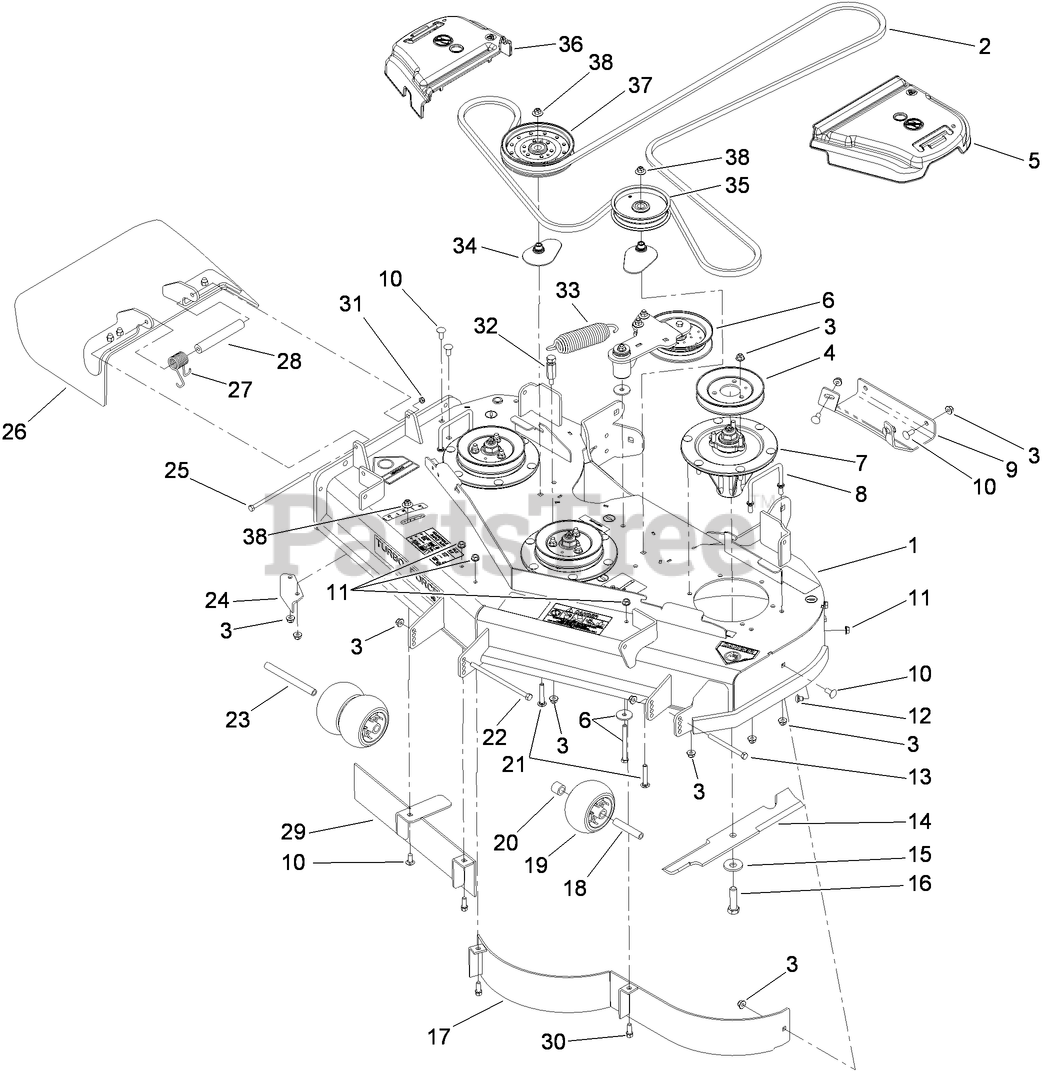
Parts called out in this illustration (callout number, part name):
1	DECK DECAL ASM
2	BELT-V
3	NUT-HF, NI
4	PULLEY
5	COVER-BELT, LH
6	IDLER ARM ASM
7	SPINDLE ASM
8	WIREFORM-COVER
9	PLATE-SKID
10	SCREW-CARR
11	NUT-HHF, WHIZ
12	SCREW-CARR
13	SCREW-HH
14	BLADE-16.5 INCH (HIGH FLOW)
15	Washer-Blade Bolt, Heavy
16	SCREW-BLADE
18	TUBE-SPANNER
19	ROLLER-SCALP, ANTI
20	TUBE-SPACER
21	BOLT-CARR, SHORT NECK
22	SCREW-HH
23	SPACER-WHEEL
24	BAFFLE-DISCHARGE
25	SCREW-HH
26	RUBBER DEFLECTOR ASM
27	SPRING-TORSION
28	SPACER
29	BAFFLE ASM
30	SCREW-HWH
31	NUT-LOCK, NI
32	ANCHOR-SPRING, TALL
33	EXTENSION-SPRING
34	SPACER-PULLEY
35	PULLEY-IDLER
36	COVER-BELT, RH
37	PULLEY-IDLER, FLAT
38	NUT-FLANGE, NI
